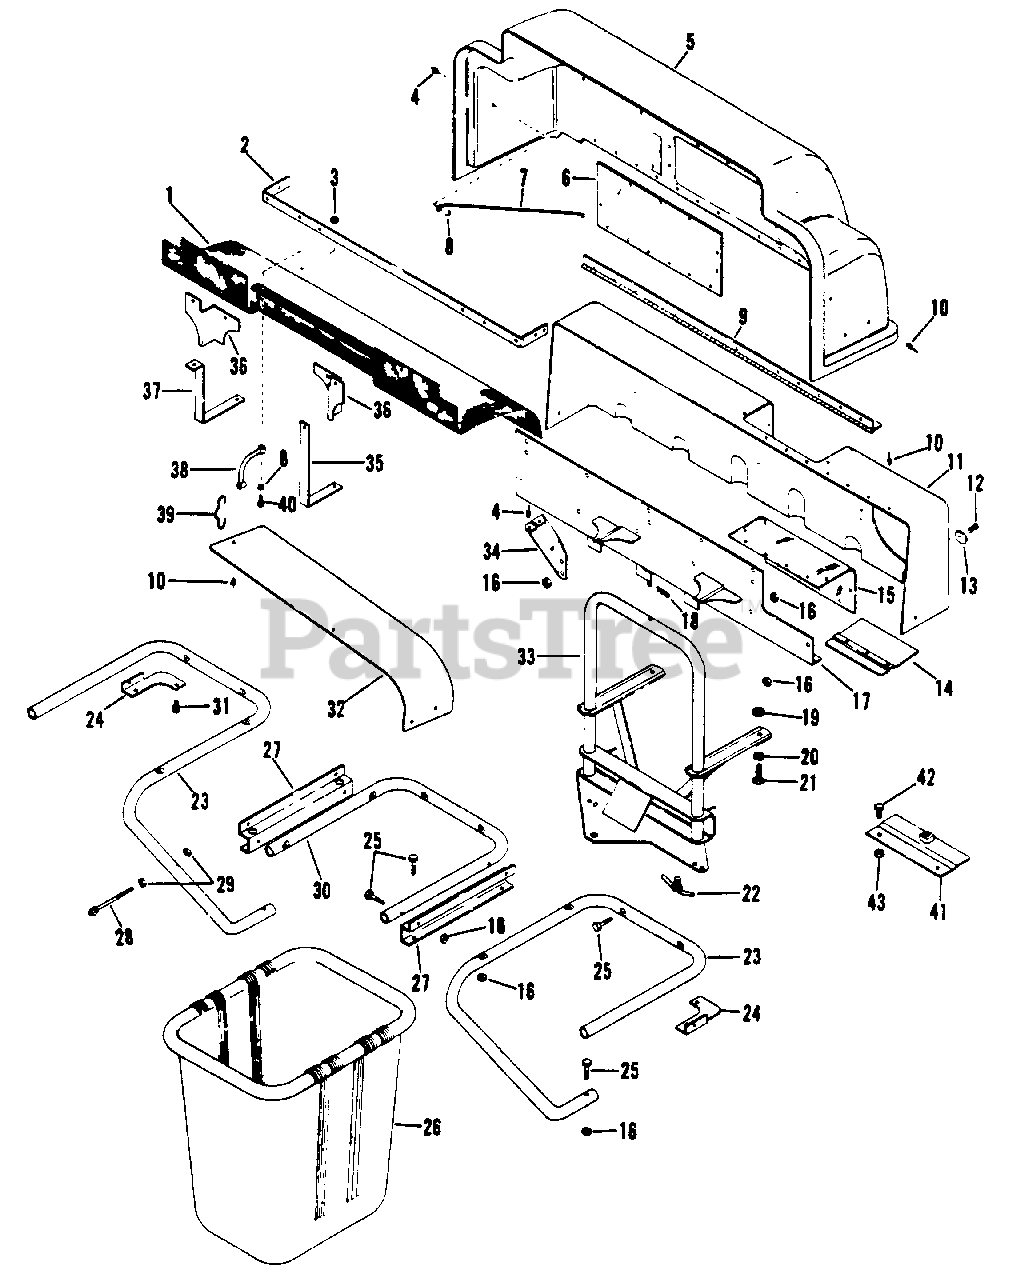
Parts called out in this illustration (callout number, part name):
1	Screen
2	Bracket, Screen Mounting
3	Nut, Lock 10-24
4	Rivet, Pop-Domed
5	Cover, Hinged
6	Window, Hinged Cover
7	Brace
8	Washer, Flat .188x.562x.049
10	Rivet, Pop-Domed
11	Cover, Stationary
12	Bolt, Hex 5/16-18x.75
13	Washer, Flat .340x1.12x.063
14	Guide, Tube
15	Window, Stationary Cover
16	Nut, Lock 5/16-18
17	Bracket, Mounting
18	Hairpin, Internal
19	Nut, Lock 3/8-16
20	Nut, Hex 3/8-16
21	Bolt, Hex 3/8-16x1.25
22	Bolt, T-Handle
23	Tube, Right
23	Tube, Left
24	Bracket, R.H. Corner
24	Bracket, L.H. Corner
25	Screw, Machine 5/16-18x1.50
26	Basket, Grass Bagger
27	Bracket, Tube
28	Eyebolt
29	Nut, Lock 1/4-20
30	Tube, Center
31	Bolt, Hex 5/16-18x.50
33	Frame, Attachment
34	Brace
35	Brace
36	Baffle, L.H.
36	Baffle, R.H.
37	Brace
38	Strap
39	Hook
40	Screw, Mach. 10-24x1.00 Rd Hd
41	Weldment, Adaptor
42	Bolt, Hex 3/8-16x.75
43	Nut, Lock 3/8-16
NS	Decal, Gravely Logo
